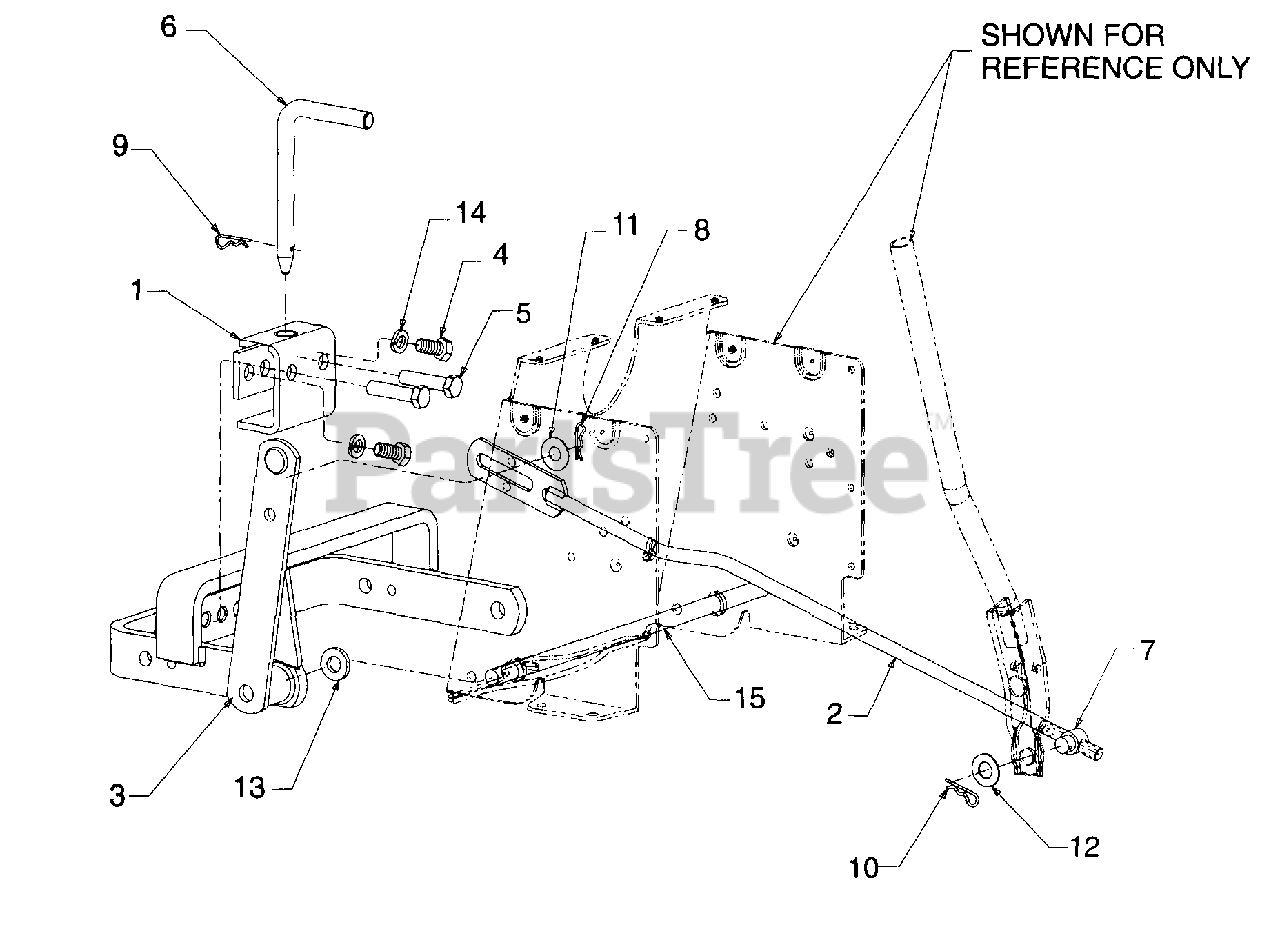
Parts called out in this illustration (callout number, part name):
1	BRKT ASM:HITCH
2	ROD ASM:LIFT
5	HHCS:1/2-13:2.25:GR5:SPEC
6	PIN:HITCH
7	ADJUSTMENT FERRULE 1/2-13
8	PIN:COT: INT .08 X 1.42
9	PIN:COT:.148 X 3.0 INTERNAL
10	PIN:COT:.092 X 1.63 INTERNAL
11	FL-WASH .531 ID X 1.25 OD X .0
12	FL-WASH .640 ID X 1.24 OD X .06
13	WASH:FLAT:.635 X 1.24 X .181
14	WASH:LOCK:1/2:REGULAR DUTY
15	ROD:.625 X 16.94 LG
